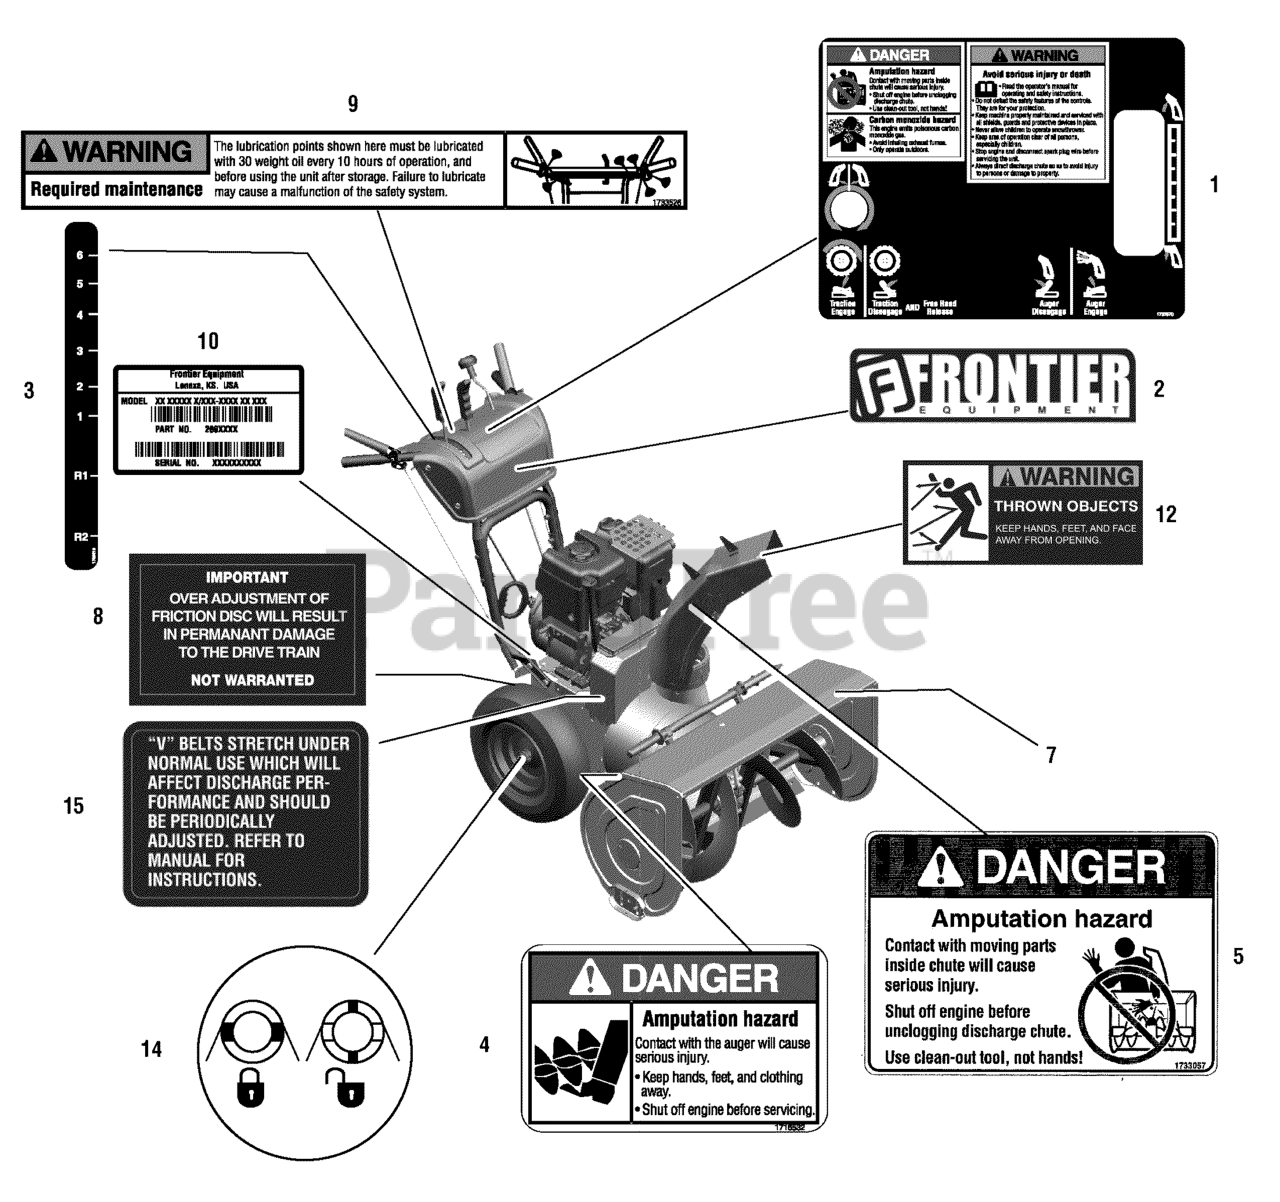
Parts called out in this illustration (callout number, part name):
1	DECAL, Dashboard
2	PLATE, FRONTIER
3	DECAL, Shift
4	DECAL, Danger Avoid Injury From Auger
5	DECAL, Danger Amputation Hazard
7	DECAL, ST8526
7	DECAL, ST9528
8	DECAL, Over Adjustment of Friction Disc
9	DECAL, Lubrication *
10	STICKER, Serial w/Bar Code
12	DECAL, Thrown Objects
14	DECAL, Wheel Lock
15	DECAL, V-Belt Adjustment
